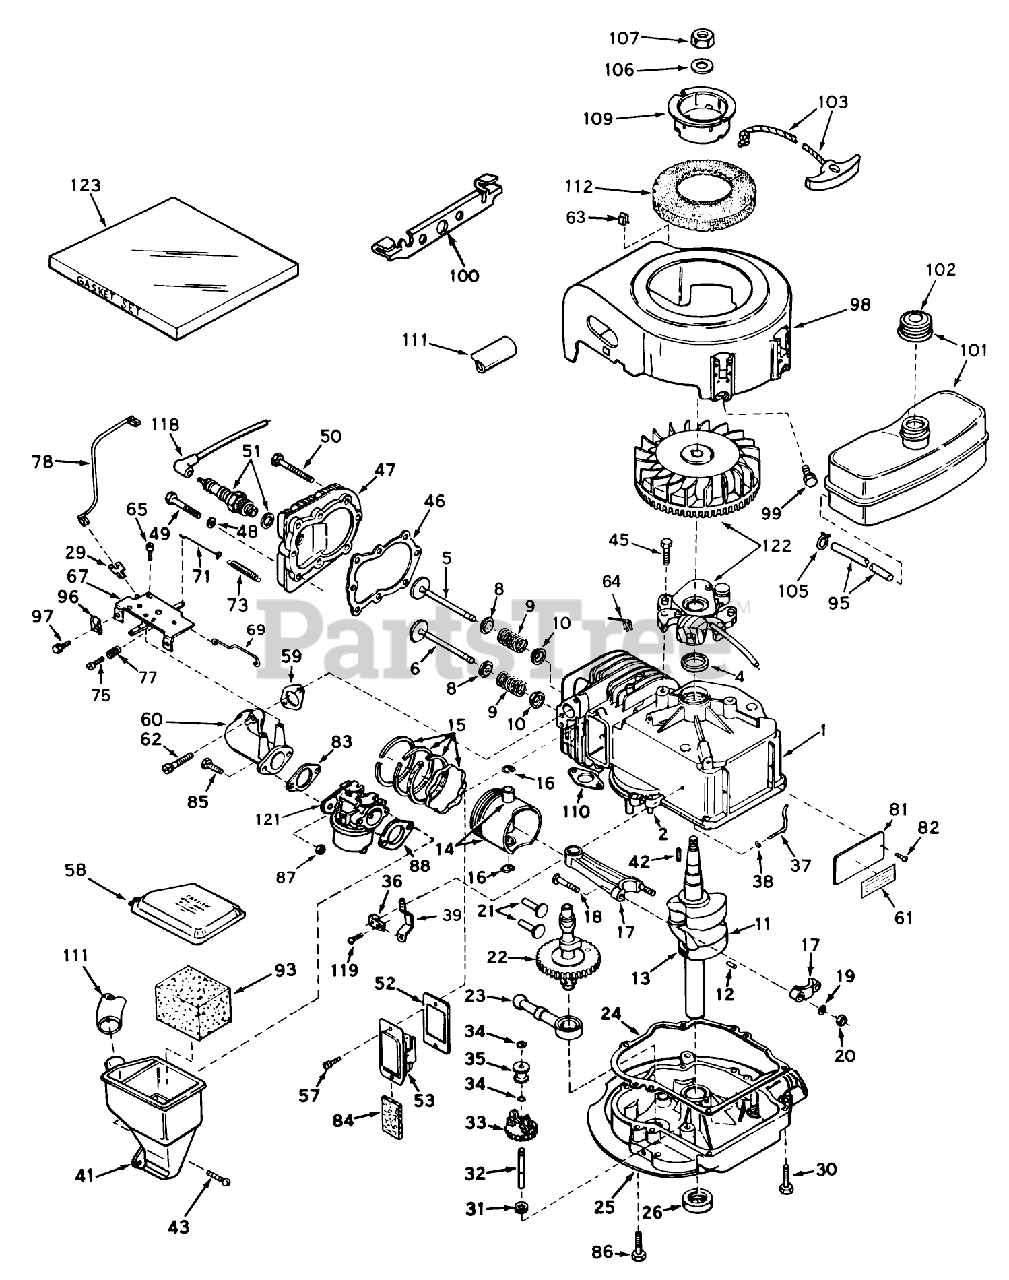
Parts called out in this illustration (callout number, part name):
1	Cylinder Assembly (Incl. Nos. 2, 4 113)
2	Pin-Dowel
4	OIL SEAL
5	Valve, Intake (Incl. Ref. #38, 39 40) (Std.)
5	Valve, Exhaust (1/32" Oversize) (Incl. Nos. 8, 9 10)
6	Valve, Exhaust (Standard) (Incl. Nos. 8, 9 10)
6	Valve, Exhaust (1/32" Oversize) (Incl. Nos. 8, 9 10)
8	Cap-Upper Valve Spring
9	Spring-Valve
10	Cap-Valve, Spring
11	Crankshaft Assy. (Incl. Ref. 12 13)(Model LAV35-40455H)
12	Pin, Groove
13	Gear, Crankshaft
14	Piston Pin Assembly (Incl. 2 of No. 16) (Std.)
14	Piston Pin Assembly (Incl. 2 of No. 16) (.010 Oversize)
14	Piston Pin Assembly (Incl. 2 of No. 16) (.020 Oversize)
15	Piston Ring Set Std.
15	Piston Ring Set .010 O.S.
15	Piston Ring Set .020 O.S.
16	Ring-Retaining, Piston Pin
17	Rod Assy., Connecting (Incl. Ref. #17)
18	Bolt, Connecting
19	Washer
20	LOCKNUT
21	Lifter-Valve
22	Camshaft (Compression Release
23	Oil Pump ASM
24	Gasket, Mounting
25	Flange Assy., Mounting (Incl. #26 32)
26	Seal Oil
29	Terminal
30	Screw (1/4-20 x 1-1/4)
31	Washer-Flat
32	Shaft-Governor
33	Governor Gear ASM
34	Ring-Retaining
35	Spool-Governor
36	Clamp-Lever, Governor
37	Rod, Governor (Incl. No. 36)
38	Washer-Flat
39	Governor Lever
41	Body, Air Cleaner
42	Key Flywheel
43	Screw, Fil. Hd. Sems
45	Screw
46	Gasket-Cylinder Head
47	CYLINDER HEAD
48	Washer
49	Screw
50	Screw Hex Hd. Cap
51	Plug, Spark (J17LM or equiv.)
52	Gasket Breather
53	Breather Assembly (Incl. Nos. 52 84)
57	Screw
58	Cover, Air Cleaner
59	Gasket, Intake
60	Pipe, Intake
61	480B GIL SNWTHWR O/
62	Screw (1/4-20 x 1)
63	51004 GIL ROTARY TI
64	Clip-Wire
65	Screw (10-24 x 9/16)
67	51089 SUPP TO MANUA
69	Link Governor
71	Link-Governor
73	Spring, Governor
75	Screw
77	Spring-Compression
78	Wire, Ground
81	IDENTIFICATION PLATE
82	Stud
83	Gasket
84	Element-Breather
86	Screw
87	Nut and Lock Washer (1/4-28)
88	Gasket-Air Cleaner
93	Element, Air Cleaner
95	Line-Fuel (8.62)
96	Conduit
97	Screw (10-32 x 3/8)
98	Housing, Blower
99	Screw (1/4-20x19/32)
100	Bracket, Shroud
101	Tank, Fuel
102	Cap, Fuel Filler
103	Rope Assy., Starter
105	Clamp-Line, Fuel
106	Washer
107	Hex Nut
109	Pulley Starter
110	Gasket Exhaust
111	Tube, Air Cleaner
112	Screen, Air
118	Cover-Spark Plug
119	Screw
121	Carburetor (Incl. No. 83)
122	Magneto
123	Gasket Set
